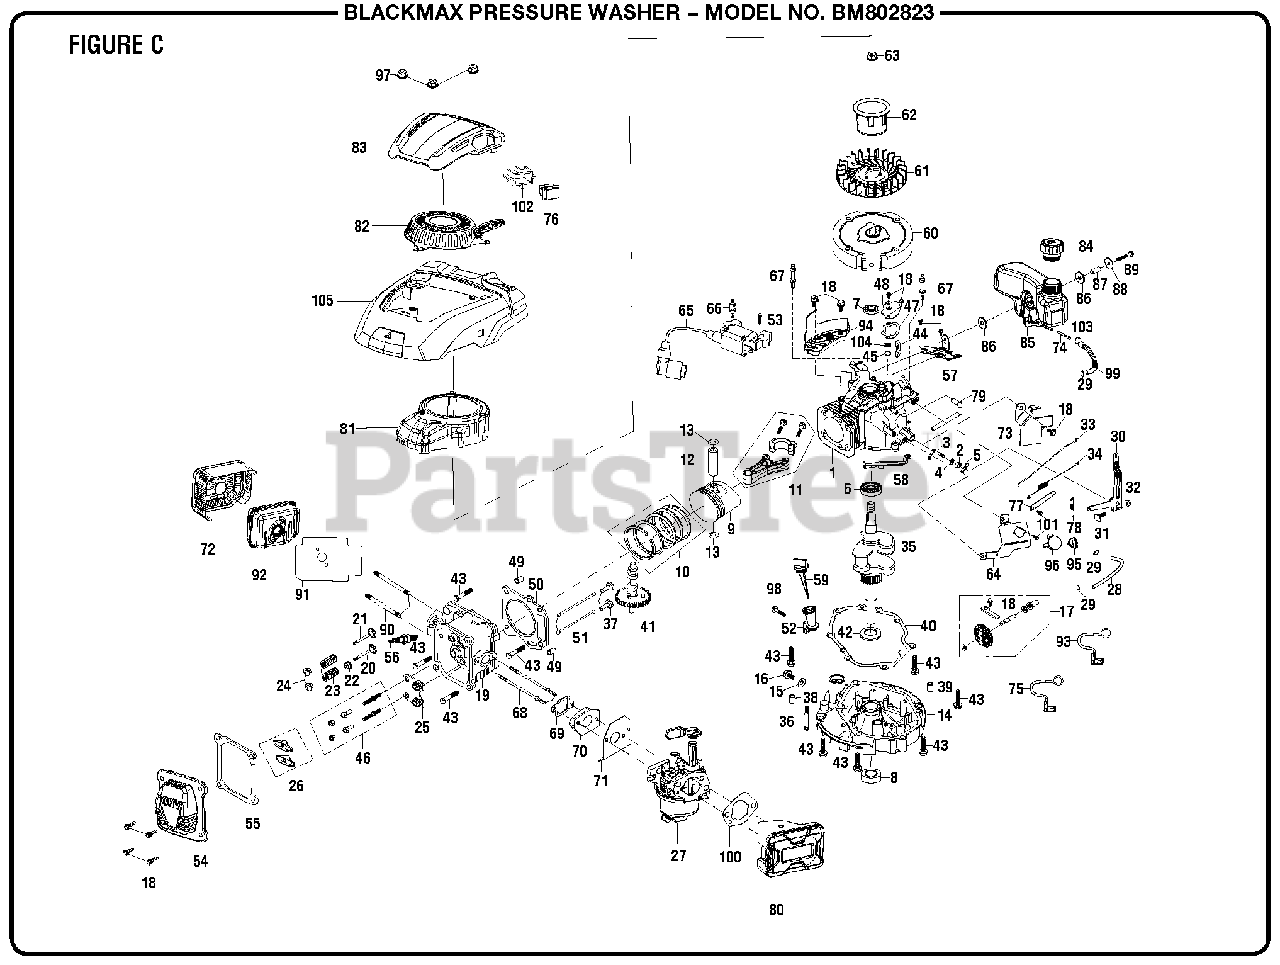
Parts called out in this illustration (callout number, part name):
2	Governor Arm Shaft Seal
3	Governor Arm Shaft
4	Governor Arm Shaft Washer
6	Ball Bearing
10	Piston Scraper Ring Set
11	Connecting Rod Assembly
13	Piston Clip
14	Crankcase Cover Assembly
15	Drain Plug Washer
17	Governor Assembly
18	Bolt (M6 x 12 mm, Hex Flange Hd.)
19	Cylinder Head
20	Inlet Valve
21	Exhaust Valve
22	Intake Valve Returner
23	Valve Spring
24	Valve Spring In Seat
25	Push Rod Guide Plate
26	Rocker Assembly
27	Carburetor Assembly
29	Fuel Line Clip
30	Governor Arm
31	Governor Arm Bolt(M6 x 21 mm, Hex Hd.)
33	Governor Rod
34	Throttle Return Spring
35	Crankshaft Assembly
36	Oil Defense Pipe
37	Valve Lifter
38	Case Cover Dowel Pin
39	Case Cover Dowel Pin
40	Case Cover Packing
41	Camshaft Assembly
42	Crankshaft Washer
43	Bolt (M8 x 50 mm)
44	Breather Filter
45	Breather Valve Cover
46	Rocker Bolt
47	Breather Chamber Gasket
48	Breather Chamber Cap
50	Cylinder Head Gasket
52	Oil Filler Extension
53	Bolt (M6 x 30 mm)
54	Cylinder Head Cover Comp
55	Headcover Packing
57	Oil Tank Stay
60	Flywheel Assembly
61	Recoil Starter Fan
62	Starter Pulley
64	Switch Plate
65	Ignition Coil Assembly
66	Ignition Coil Bolt Stud
67	Recoil Starter Bolt Stud
69	Intake Packing
70	Carburetor Insulator
71	Carburetor Packing
72	Out Muffler Shield
73	Upper Shroud Assembly
75	Flameout Wire
77	Wire Harness Clip
78	Governor Spring
79	Breather Tube
80	Air Cleaner Assembly
82	Recoil Starter Comp
83	Upper Fan Cover
84	Fuel Tank Cap
85	Fuel Tank Assembly
86	Isolation Pad
87	Fuel Tank Bushing
88	Fuel Tank Washer
89	Bolt (M8 x 45 mm)
91	Exhaust Packing
92	Muffler Comp
93	Flameout Wire
95	Fuel Valve Knob
96	Fuel Valve Bezel
98	Bolt (M8 X 20 mm)
100	Carburetor Spacer
101	Bolt (M6 x 25 mm)
102	Switch Bracket
103	Fuel Line Clip
104	Breather Spring
105	Lower Fan Cover
